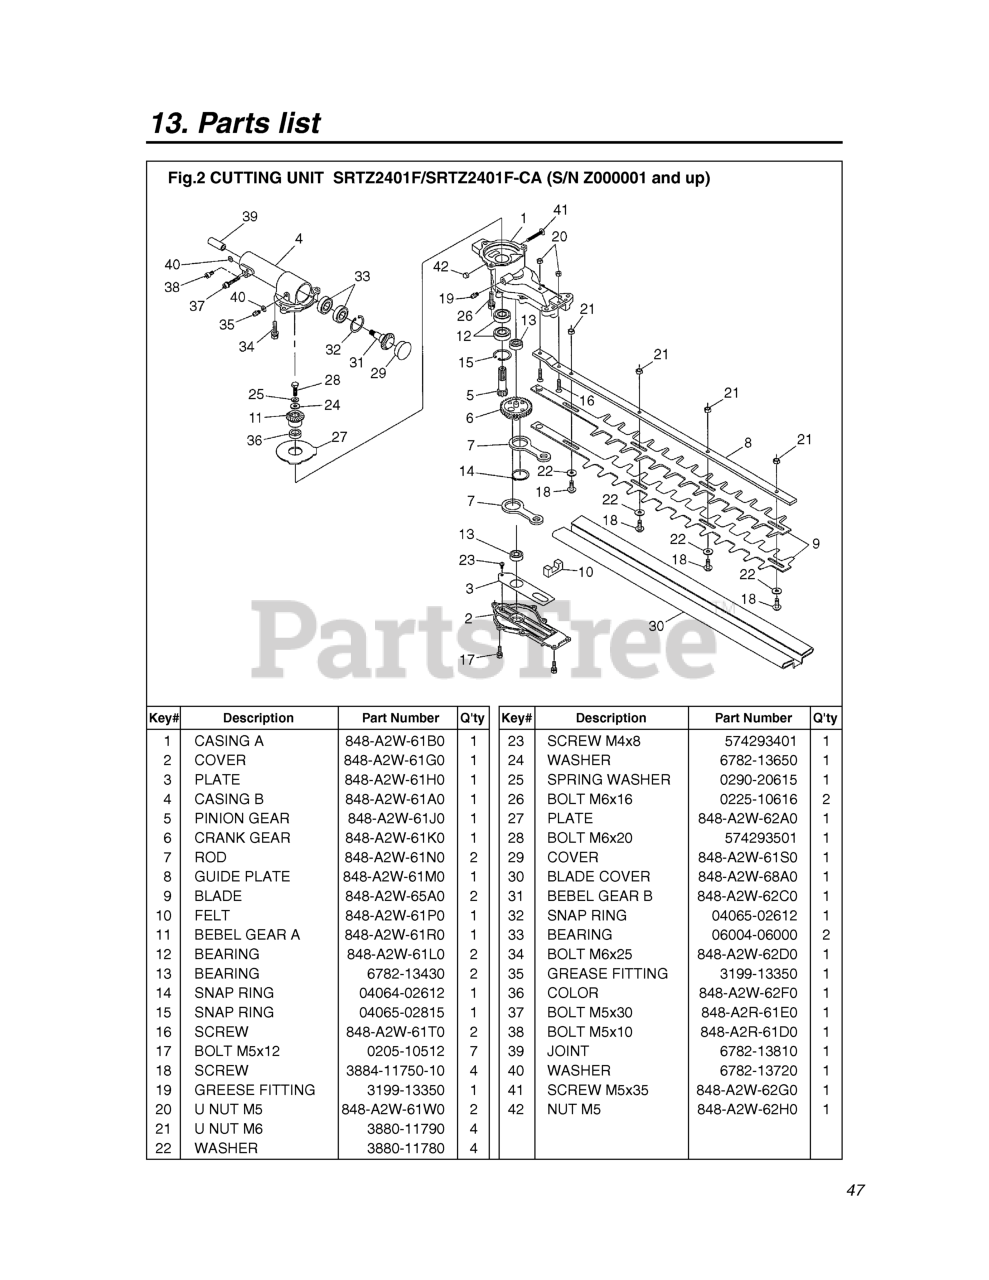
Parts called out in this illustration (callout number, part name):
1	CASING A
2	COVER
3	PLATE
4	CASING B
5	PINION GEAR
6	CRANK GEAR
7	ROD
8	GUIDE PLATE
9	BLADE
10	FELT
11	BEBEL GEAR A
12	BEARING
13	BEARING
14	SNAP RING
15	SNAP RING
16	SCREW
17	BOLT
19	FITTING, GREASE
20	U NUT
21	NUT
22	WASHER
24	WASHER, 6X15X2.0
25	WASHER M6
26	BOLT, M6 x 16
27	PLATE
29	COVER
30	BLADE COVER
31	BEBEL GEAR B
32	SNAP RING
33	BEARING
34	BOLT
35	FITTING, GREASE
36	COLOR
37	BOLT
38	BOLT
39	JOINT
40	WASHER
41	SCREW
42	NUT
